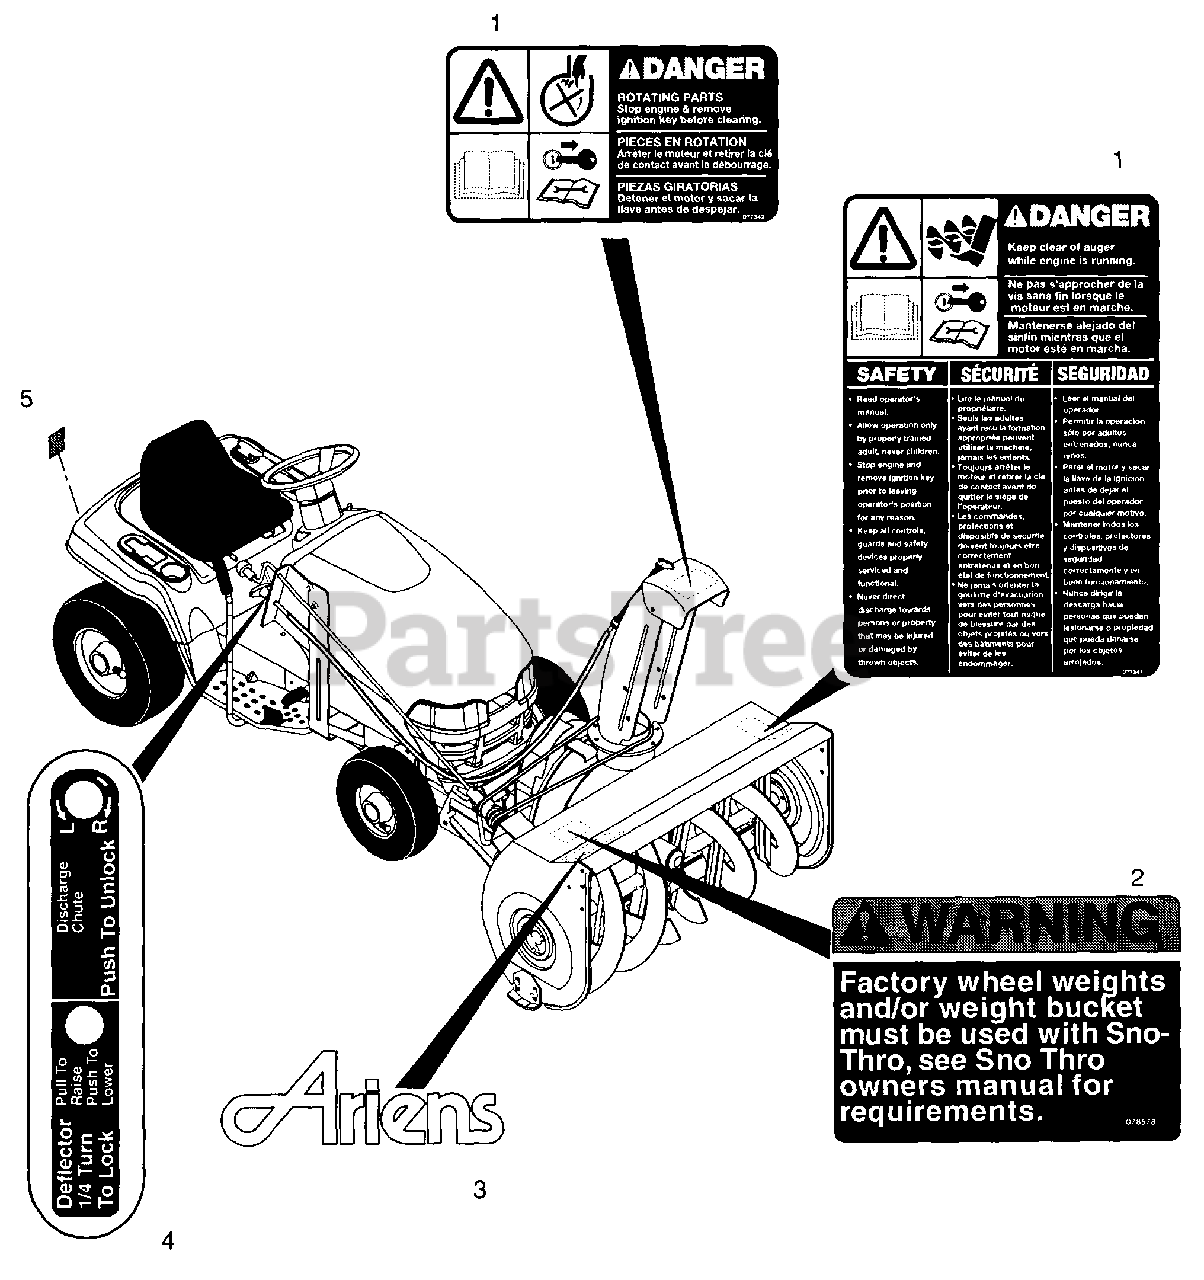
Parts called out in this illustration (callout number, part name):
1	DECAL SET - DANGER
2	WARNING WHEEL WEIGHT DECAL
3	DECAL - ARIENS
4	CHUTE CRANK DECAL
5	REFLEX REFLECTOR
